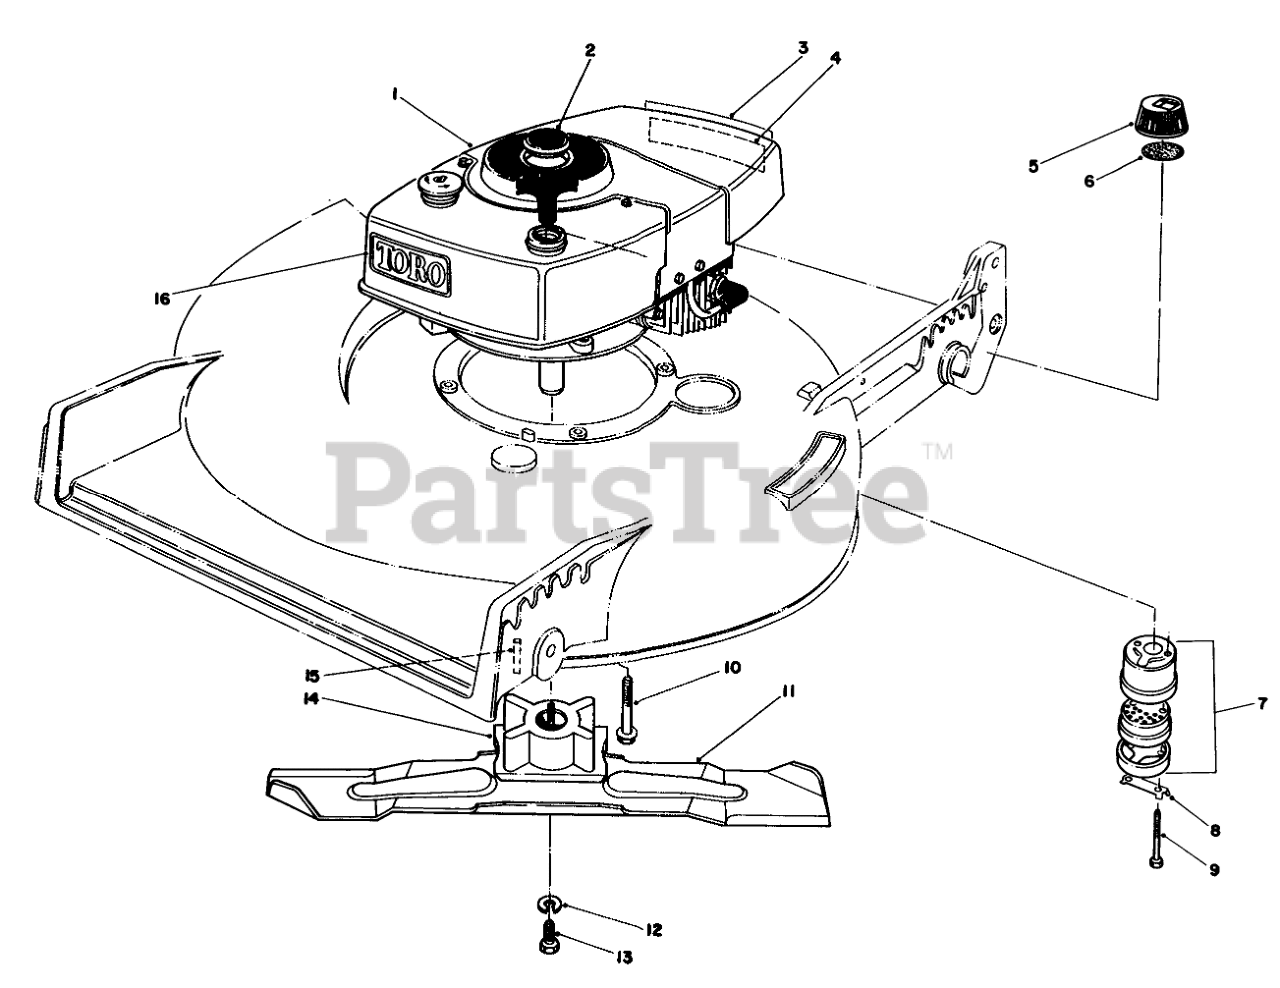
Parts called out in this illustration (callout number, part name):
1	Engine
2	Plug Button
3	Decal-Primer
4	Decal Maintenance
5	Gas Cap Assembly (Incl. Ref. #6)
6	GAS CAP GASKET
7	Muffler Assembly (Incl. Ref. #8 & 9)
8	CLIP - LOCKING
9	SCREW-HH
10	3/8-16 X 2 CAPSCREW
11	BLADE-21in
12	WASHER-LOCK
13	SCREW-BLADE
14	BLADE RETAINER(DEEP)
15	KEY-SQUARE
16	Decal Tow
